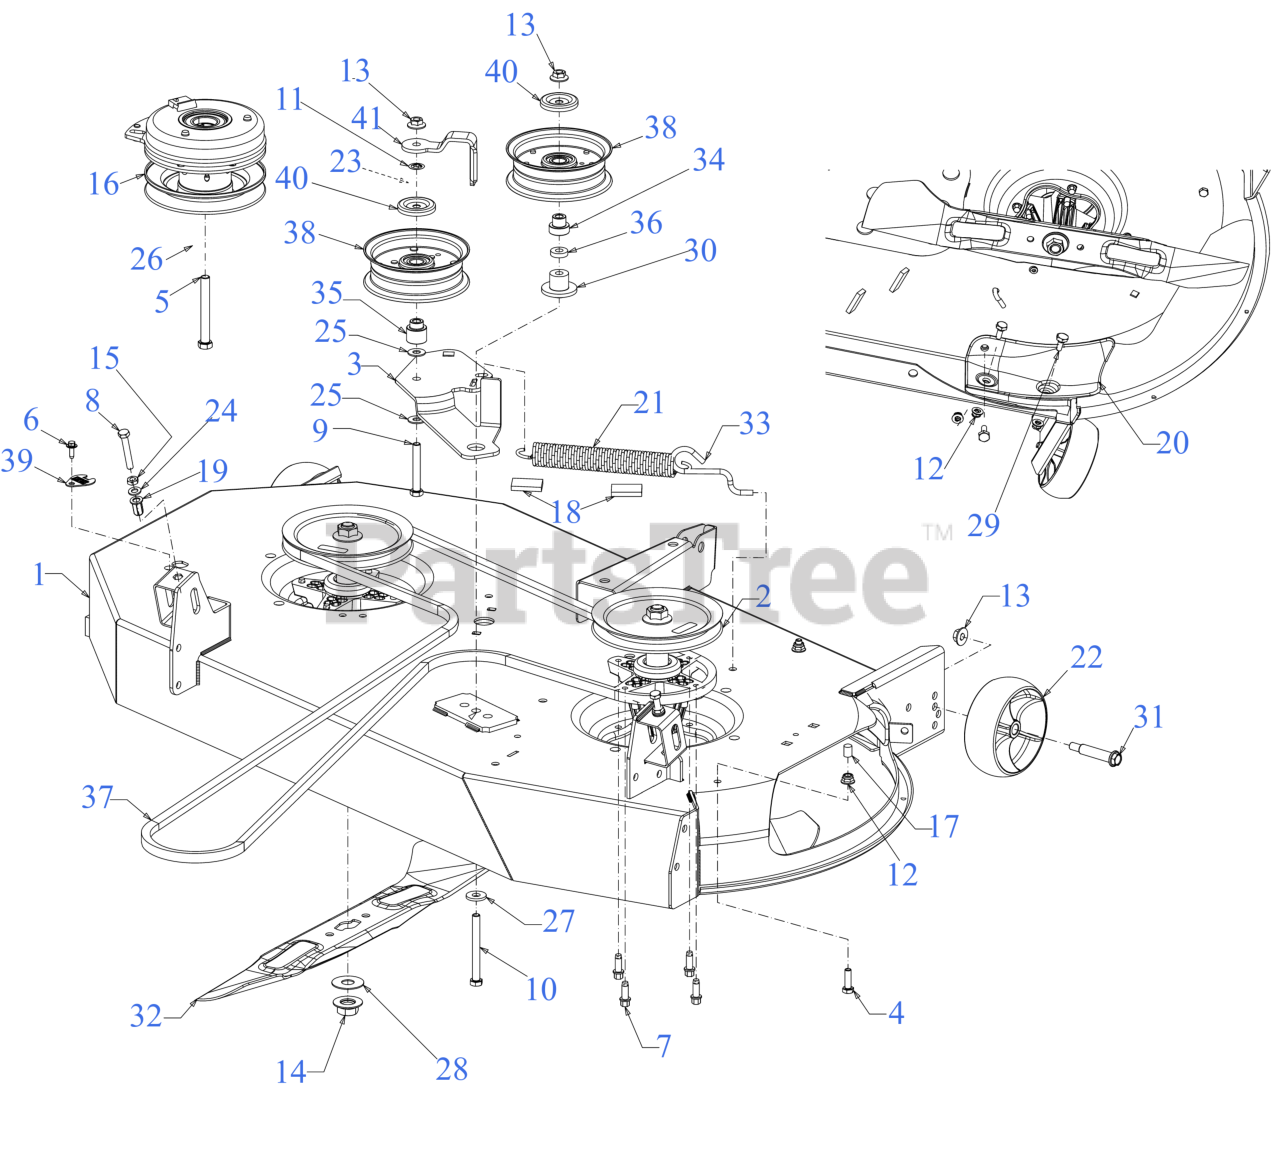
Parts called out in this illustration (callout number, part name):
1	46" FAB DECK SHELL
2	SPINDLE ASSEMBLY (6.93) (S SHAPE)
3	DECK IDLER BRACKET
4	SCREW 5/16-18 x 1.0 GR5
5	SCREW 7/16-20 x 3.5 GR5
6	SCREW M6-1 x .625
7	SCREW 5/16-18 x .875
8	SCREW-FULL THREAD 5/16-18 GR5
9	HEX SCREW-3/8-16X2.5 GR5
10	SCREW 3/8-16 x 3.50 GR5
12	FLANGE LOCK NUT 5/16-18
13	FLANGE LOCK NUT
14	HEX FLANGE NUT 5/8-18 GR5
16	ELECTRIC PTO CLUTCH
18	FOAM TAPE .75" WIDE x .25" THICK
19	NUT RIVET 5/16-18
20	DISCHARGE BAFFLE
21	EXTENSION SPRING
22	DECK WHEEL (5.0 DIA x 1.875)
23	FLAT WASHER .385 x 1.00 x .135
24	FLAT WASHER
25	FLAT WASHER
26	FLAT WASHER .445 x 1.248 x .170
27	FLAT WASHER .406ID X1.0 OD
28	FLAT WASHER .635X1.585X.062 HDN
29	SHOULDER SCREW
30	SHOULDER SPACER
31	SHOULDER BOLT (.50 X 2.0 x 3/8 -16)
32	23.25" BLADE (2IN1) (S SHAPE CENTER HOLE)
32	Cub Cadet 46" HI LIFT BLADE SET (S SHAPE CENTER HOLE)
32	23.25" XTREME BLADE (2IN1) (S SHAPE CENTER HOLE)
32	Cub Cadet 46" XTREME BLADE SET (S SHAPE CENTER HOLE)
32	23.25" LOW LIFT BLADE (S SHAPE CENTER HOLE)
32	Cub Cadet 46" LOW LIFT BLADE SET (S SHAPE CENTER HOLE)
33	DECK SPRING HOOK
34	SHOULDER SPACER
35	SHOULDER SPACER
37	V-BELT A SEC x 120.8
37	Cub Cadet 46" RZT DECK BELT
38	IDLER PULLEY 4.50" DIA
39	DECK WASH PLUG
40	IDLER PULLEY CAP
41	BELT KEEPER
